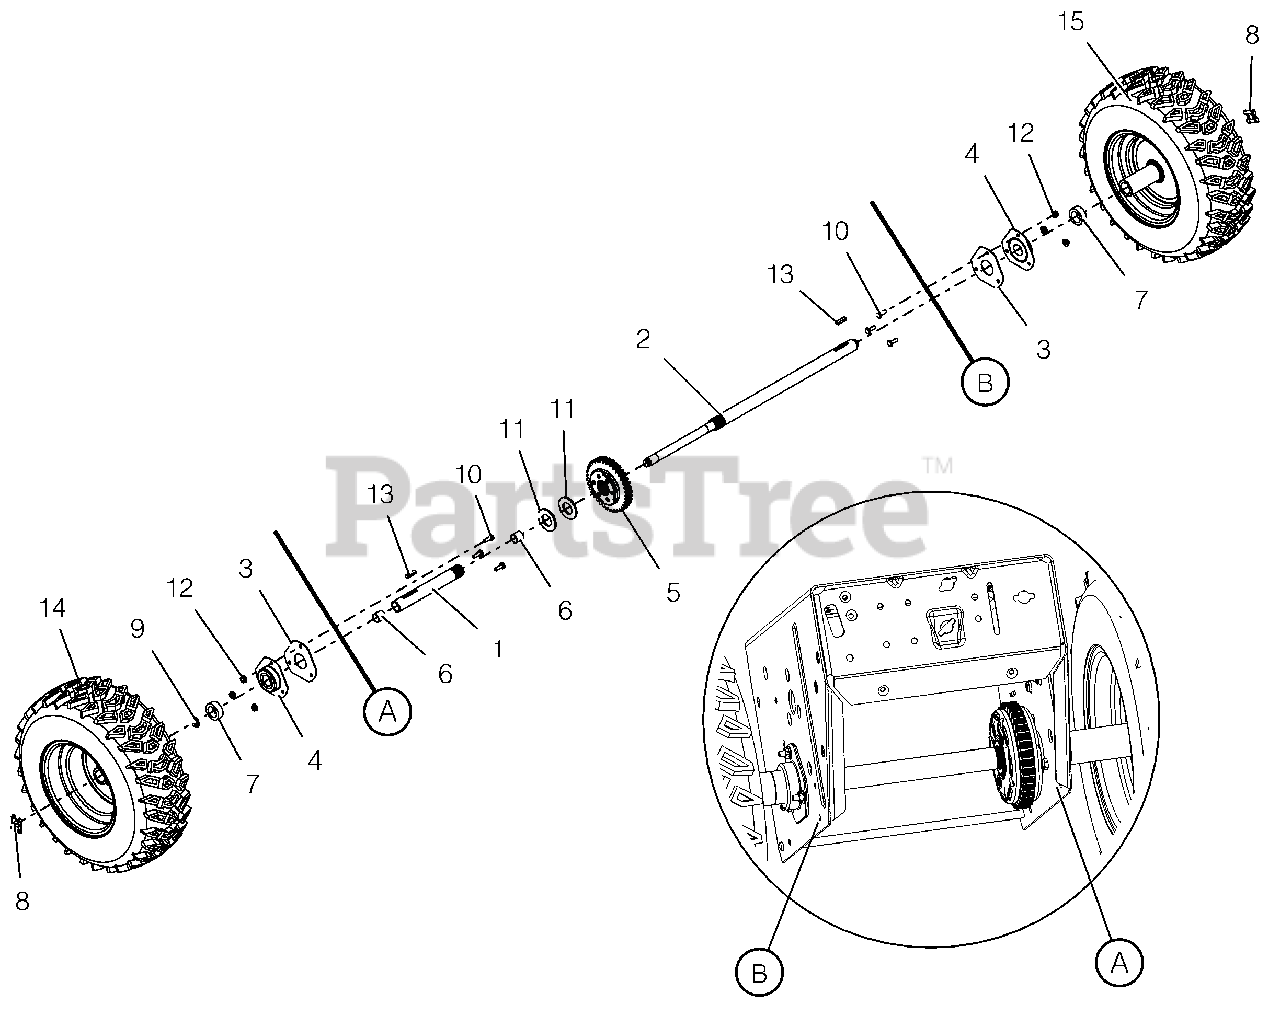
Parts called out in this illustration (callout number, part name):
1	AXLE, SHORT-AUTO W/BUSHINGS
2	AXLE, LONG-PRO AUTO DIFF
3	PLATE, BEARING SPACER
4	BRG-FLG 1.003/1.000 3 BOLT
5	DIFFERENTIAL, AUTOMATIC
6	BSHG-SLV .706X.764X.75 BRZ
7	SPACER, PRO AXLE BEARING
8	CLIP, SNAP .625 DIA
9	RG-RTNG-EXT .625X.042
10	@BLT-HEX .25-20X.75 GR5 YWZC
11	WSHR-FL-STL- 1.062X2.0X.134 YZ
12	NUT-LK-CTR-FLG .25-20 YWZC
13	KEY-RECT .25X.188X1.00
14	TIRE/WHEEL,RH 16X6.5-8 DIFF T2
15	TIRE/WHEEL,LH 16X6.5-8 DIFF T2
